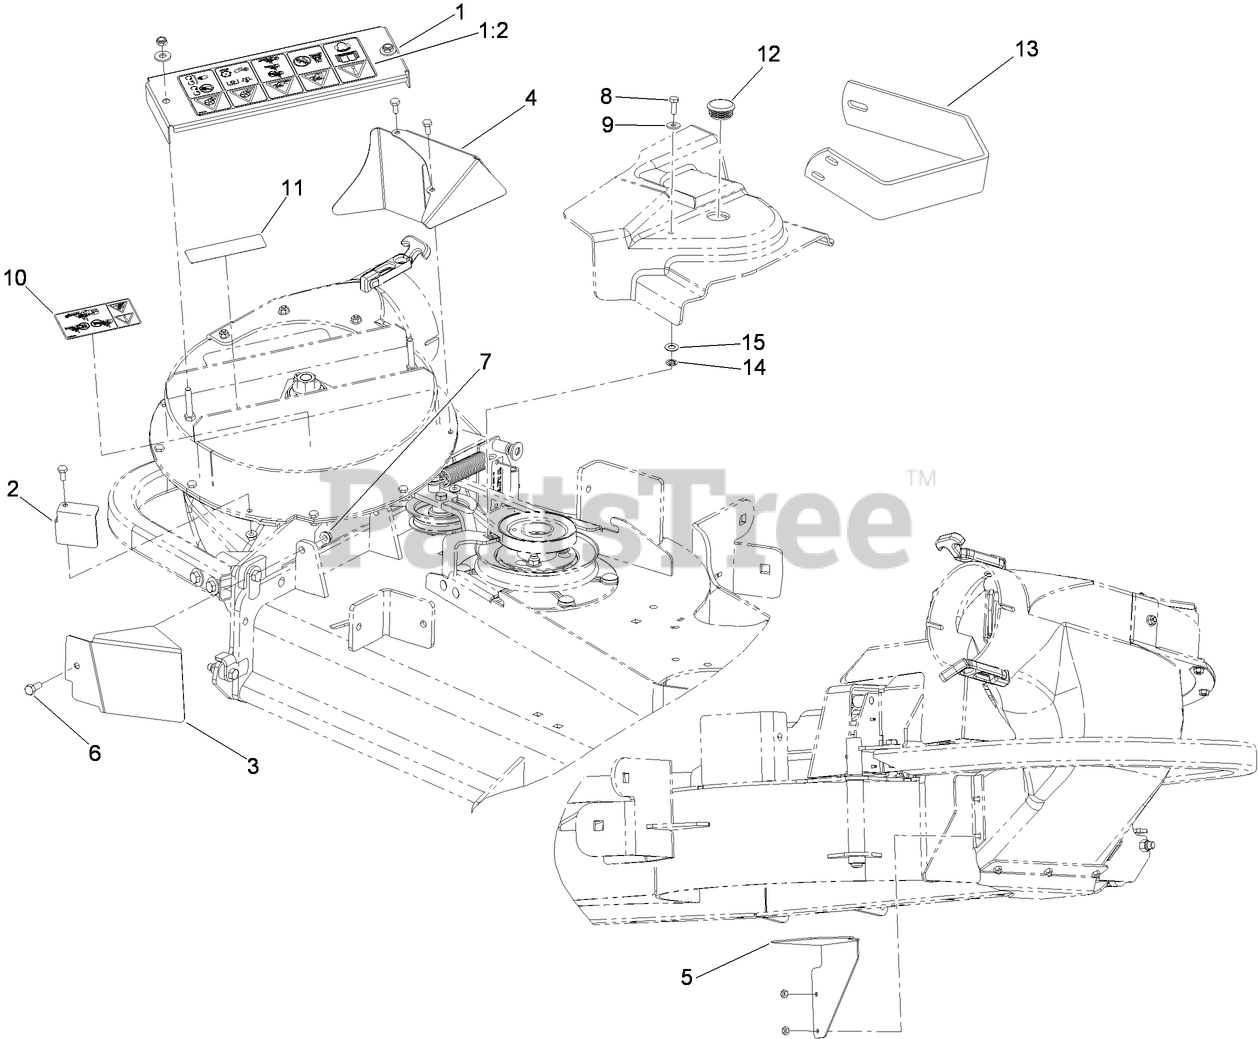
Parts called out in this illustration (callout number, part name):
1	COVER-BEARING
1:2	DECAL-DANGER
2	GUARD-LEFT
3	GUARD-FRONT
4	GUARD-BACK
5	GUARD-LOWER
6	SCREW-HH
7	NUT-HF
8	SCREW-HH
9	WASHER-FLAT
10	DECAL-WARNING
11	DECAL-MISSING, COVER
12	PLUG-PLASTIC
13	GUARD-MUFFLER
14	NUT-RETAINER
15	WASHER-FLAT
